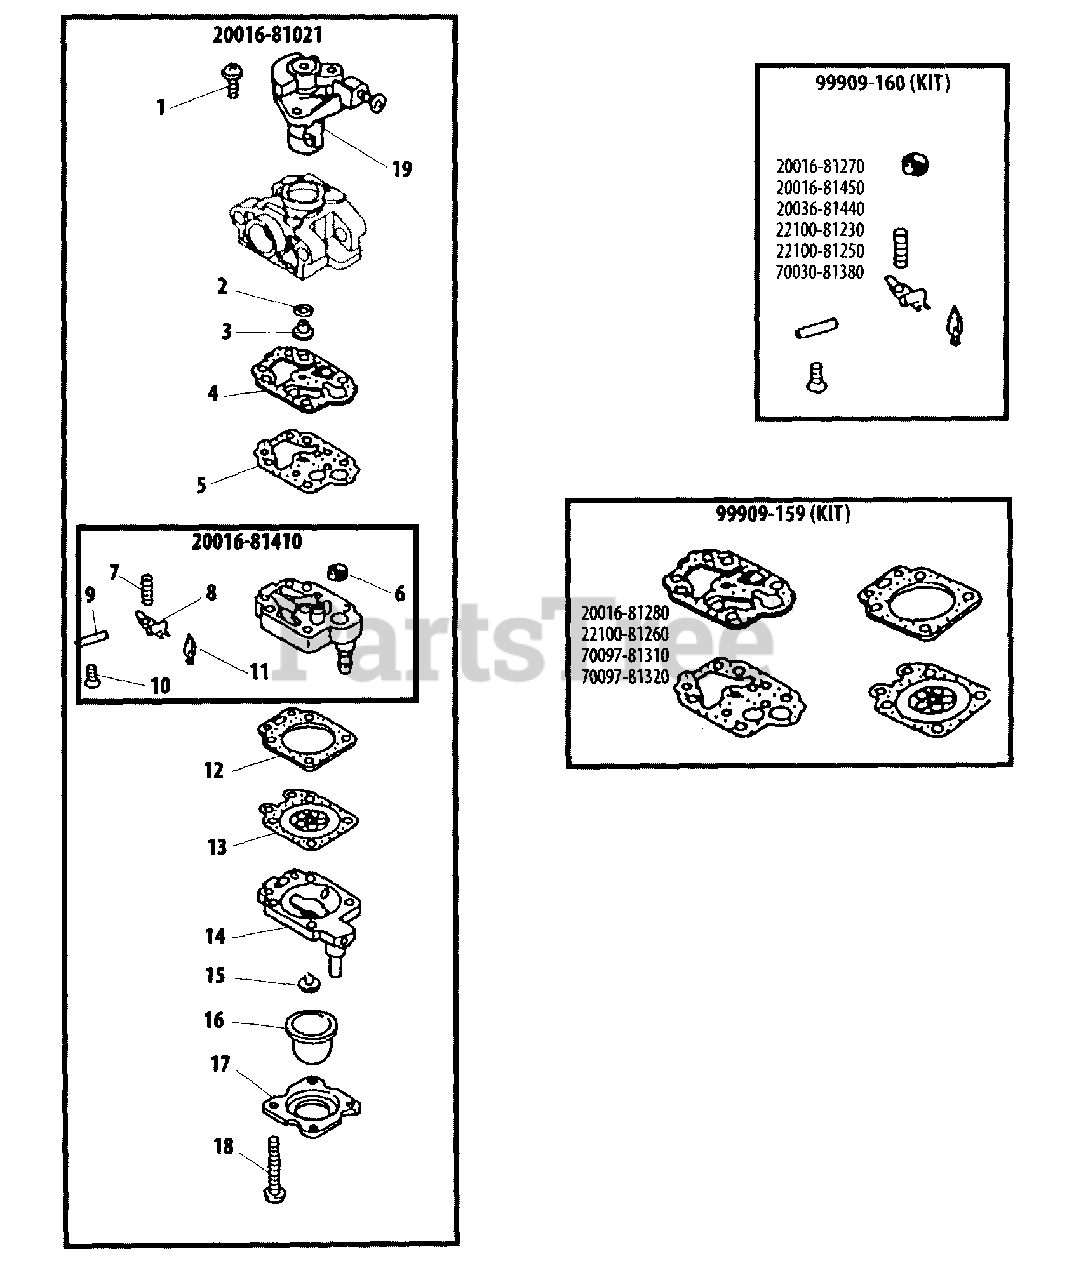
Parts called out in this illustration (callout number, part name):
1	SCREW, THROTTLE COLLAR
2	O-RING
3	JET, MAIN
4	GASKET, PUMP
5	DIAPHRAGM, PUMP
6	SCREEN, FUEL INLET
7	SPRING, METERING LEVER
8	LEVER, METERING
9	PIN, METERING LEVER
10	SCREW
11	VALVE, INLET NEEDLE
12	GASKET, METERING DIAPHRAGM
13	DIAPHRAGM, METERING
14	BODY ASSY, PURGE
15	VALVE, CHECK
16	BULB, PURGE
17	RETAINER, PURGE BULB
18	SCREW
19	VALVE ASSY, THROTTLE
20016-81021	CARBURETOR
20016-81410	BODY ASSY, PUMP
99909-159	GASKET / DIAPHRAGM KIT
99909-160	VALVE KIT, INLET NEEDLE
